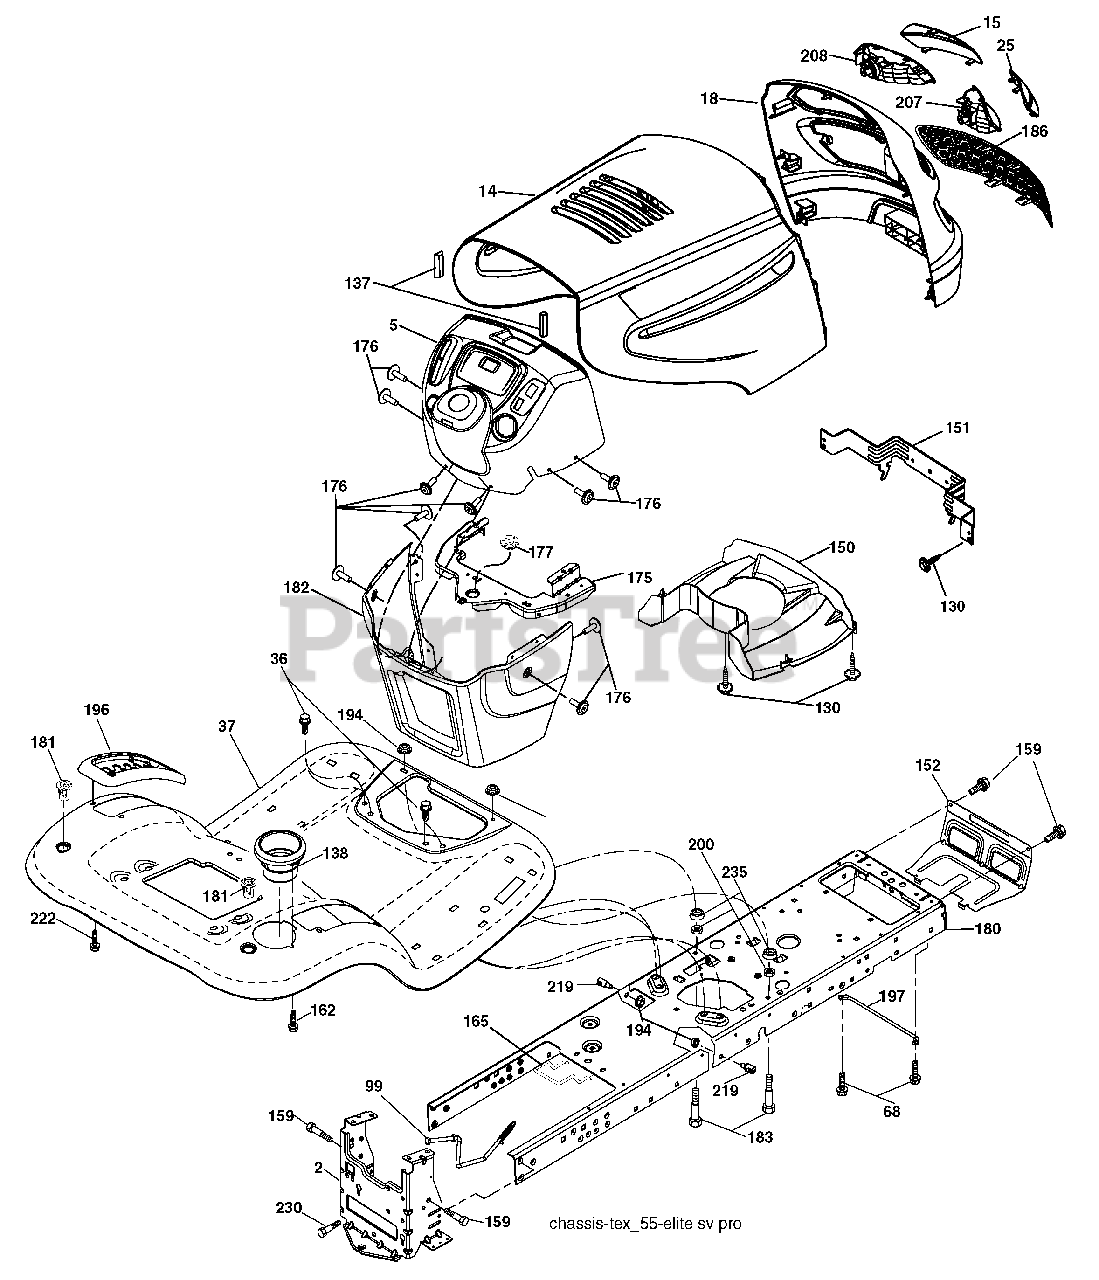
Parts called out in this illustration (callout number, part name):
2	Drawbar
5	Dash
14	Hood
15	Lens Grille LH
18	Grille
25	Lens Grille RH
36	Screw 5/16-18 x 3/4
68	Screw Thdrol 5/16-18 x 1/2
99	Rod Asm Bypass
130	Screw 10 x 3/4 Single Lead-Hex
137	Bumper Hood
138	Cupholder
150	Duct Heat Hood
151	Bracket Pivot
152	Shield Browning/Debris
159	Screw Hexwsh Thdrol 3/8-16 x 3/4
162	Screw Hex Wsh Hi-Lo 1/4 x 1/2
175	Crossmember
176	Screw 10-24 x 5/8 Wshd Qdrx
177	Bushing Steering
181	Bushing Mtg. Fender Crgo.
182	Dash Lower
183	Bolt Fin Hex 5/16-18 x 1-1/4
186	Insert Grille
194	Nut Lock Hex Flange 5/16-18
196	Console Asm. Deck Lift
197	Rod Pivot Chassis
200	Nut center Lock 5/16-18
207	Bezel Grille RH
208	Bezel Grille LH
219	Stud Fastener
222	Screw Thd Roll 1/4-20 x 5/8
230	Bolt Shoulder 5/16-18
235	Spacer Fender
